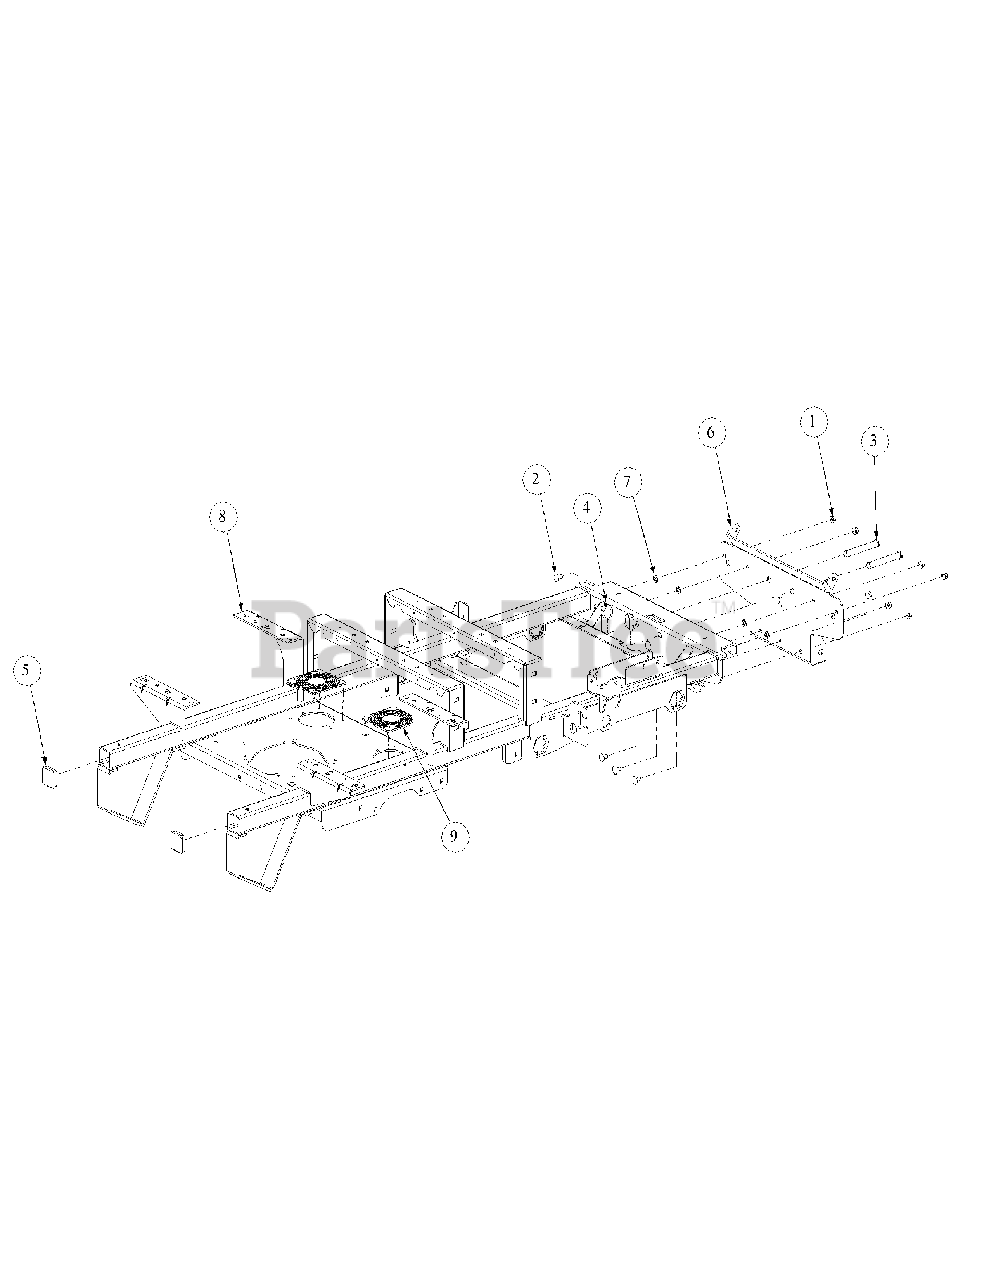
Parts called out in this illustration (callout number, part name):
1	Hex Nut, 3/8-16 Flange Lock
2	Carriage Bolt, 3/8-16 x .75 Long
3	Clevis Pin, .625 Dia x 4.375 Long
4	Linch Pin, 3/16 Dia.
5	Plug, Square Tube
6	Bracket Assembly, Frame, Front
7	Push Retainer, 3/8"-Thread Stud
8	Frame Assembly
9	Fan Pump Guard
